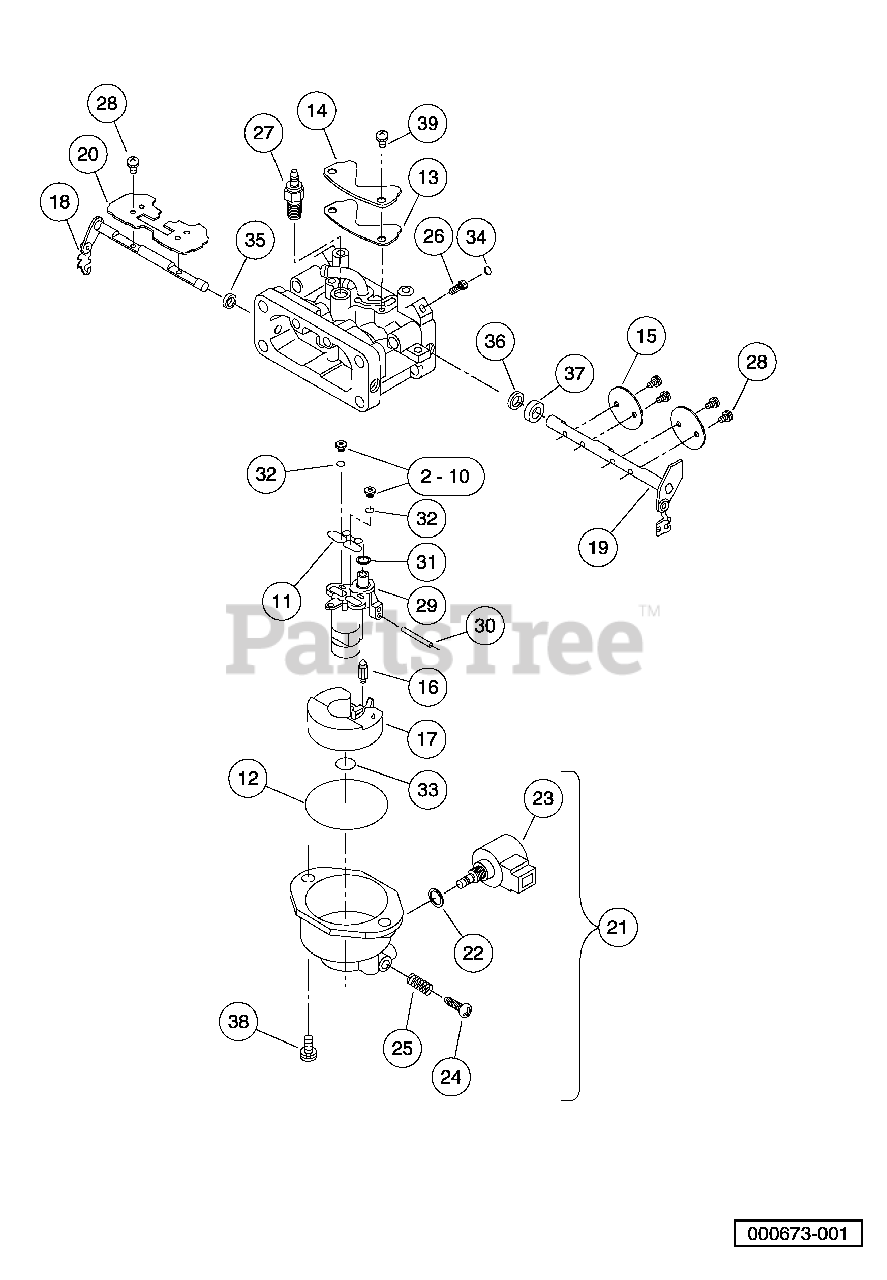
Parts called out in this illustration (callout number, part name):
1	Asm, Carburetor, Fh680d
2	Kit, Jet, 6600 Ft +, Fh680d
3	Jet, Push In #96, FH680D (6600 ft and higher (2000 m and higher))
4	Kit, Instructions Jet, Push In
5	Kit, Jet, 3300-6600 Ft, Fh680d
6	Jet, Push In #99, FH680D (3300-6600 ft (1000-2000 m))
7	Kit, Instructions Jet, Push In
8	Kit, Jet, 0-3300 Ft, Fh680d
9	Jet, Push In #102, FH680D (0-3300 ft (0-1000 m))
10	Kit, Instructions Jet, Push In
11	Gasket, Fh680d
12	Gasket, Carburetor, Dia. 52
13	Gasket, Cover, Fh680d
14	Cover, Slow Passage, Fh680d
15	Valve, Throttle, Fh680d
16	Valve, Float, Fh680d
17	Float, Carburetor, Fh680d
18	Shaft, Carburetor, Fh680d
19	Shaft, Carburetor, Throttle
20	Valve, Carburetor, Fh680d
21	Asm, Chamber, Float, Fh680d
22	Gasket, Carburetor, Fh680d
23	Solenoid, Carburetor, Fh680d
24	Screw, Drain, Carburetor
25	Spring, Carburetor, Fh680d
26	Needle, Jet, Fh680d
27	Heater, Carburetor, Fh680d
28	Screw, Carburetor, M3 X 6
29	Spacer, Carburetor, Fh680d
30	Pin, Carburetor, Fh680d
31	O-ring, Carburetor, Dia. 6.5
32	O-ring, Carburetor, Fh680d
33	O-ring, Carburetor, Dia. 9
34	Plug, Expansion, Carburetor
35	Seal, Carburetor, Dia. 5.9
36	Seal, Carburetor, Fh680d
37	Collar, Carburetor, Fh680d
38	Screw, Carburetor, M5
39	Screw, Carburetor, M4
